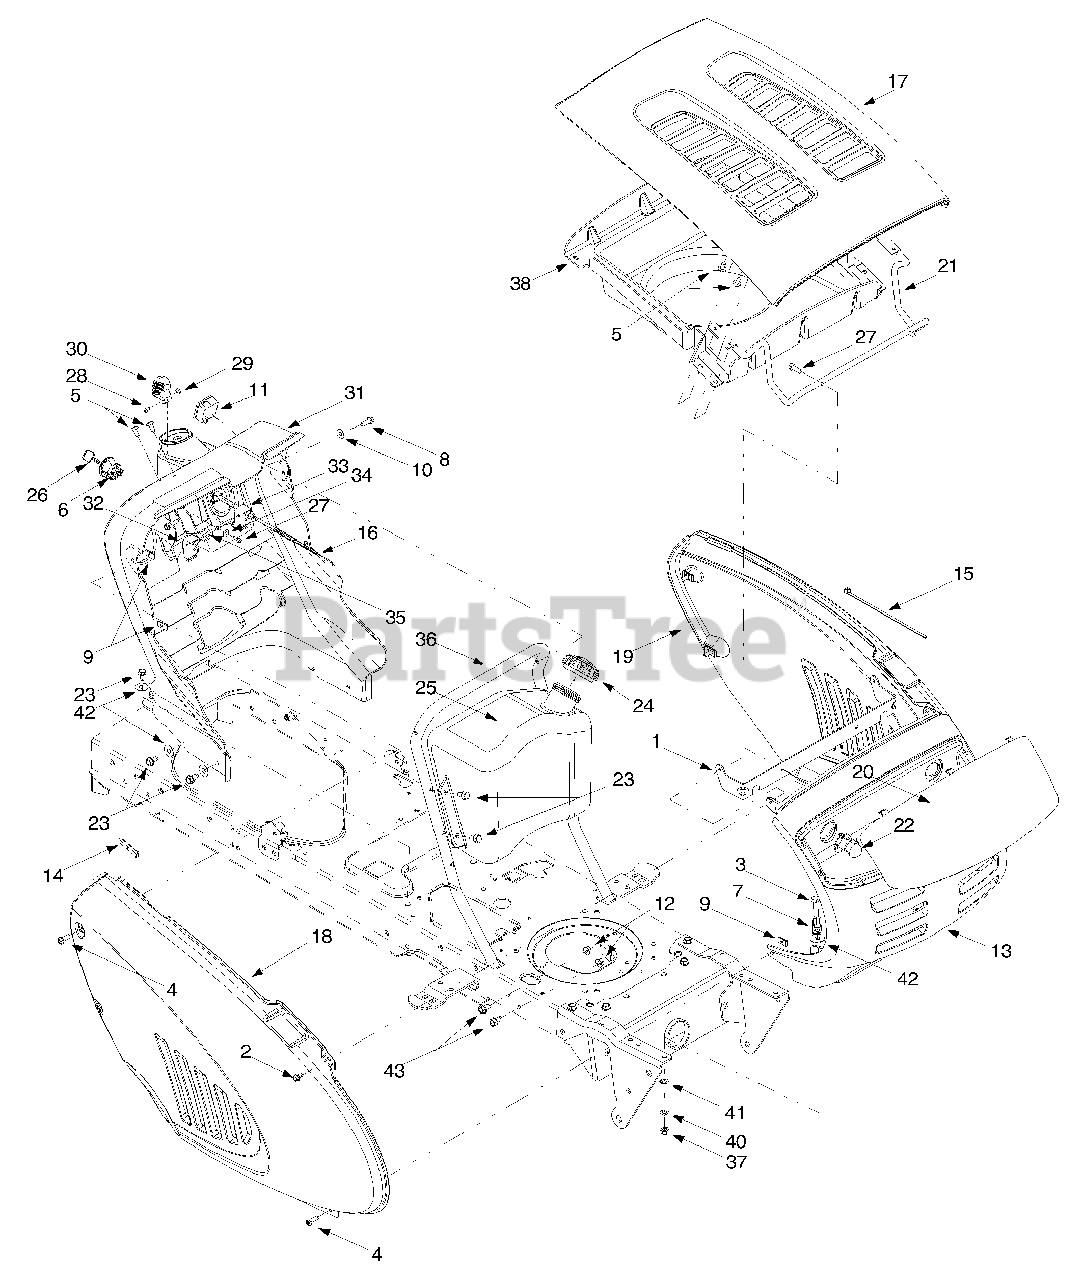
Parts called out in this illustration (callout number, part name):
2	Self-tapping Screw, 1/4-20 x .5
3	Hex Cap Screw, 5/16-18 x 1.25
4	Phillips Pan Screw, 1/4-20 x .75
5	Truss Phillips Screw, 1/4-20 x .625
6	Ignition Switch
7	Clamp, 9/16
8	Self-tapping Screw, 1/4-20 x .75
9	U-type Speed Nut, 1/4-20
10	Bell Washer, .265 x .75 x .062
11	Systems Indicator Monitor
12	Hex Nut, 5/16-18
13	Grille (9-style)
14	Trim Strip, 4
15	Cable Tie, 3/16 x .05 x 7.4
16	Choke Knob/Cable (Model G609G)
21	Hood Hinge Rod
22	Headlight Assembly
23	Self-tapping Screw, 5/16-18 x .625
24	Fuel Cap
25	Fuel Tank, Three-gallon
26	Ignition Key w/ plastic cover
27	Self-tapping Screw, 1/4-15 x .75
28	Truss Phillips Screw, #8-32 x .375
29	Hex Nut, #8-32
30	Throttle Control Knob
31	Dash Panel, 8/9-style, Manual PTO
32	Cruise Control Button
33	Parking Brake Button
34	Flat Washer, 9/32 x 1/2 x 1/16
35	Brake/Cruise Pivot Rod
38	Hood Plenum (Model G609G)
40	Lock Washer, 5/16
41	Speed Nut, .3125
42	Flat Washer, .349 x 1.0 x .063
43	Screw, 5/16-18 x .875 (Grade 5)
